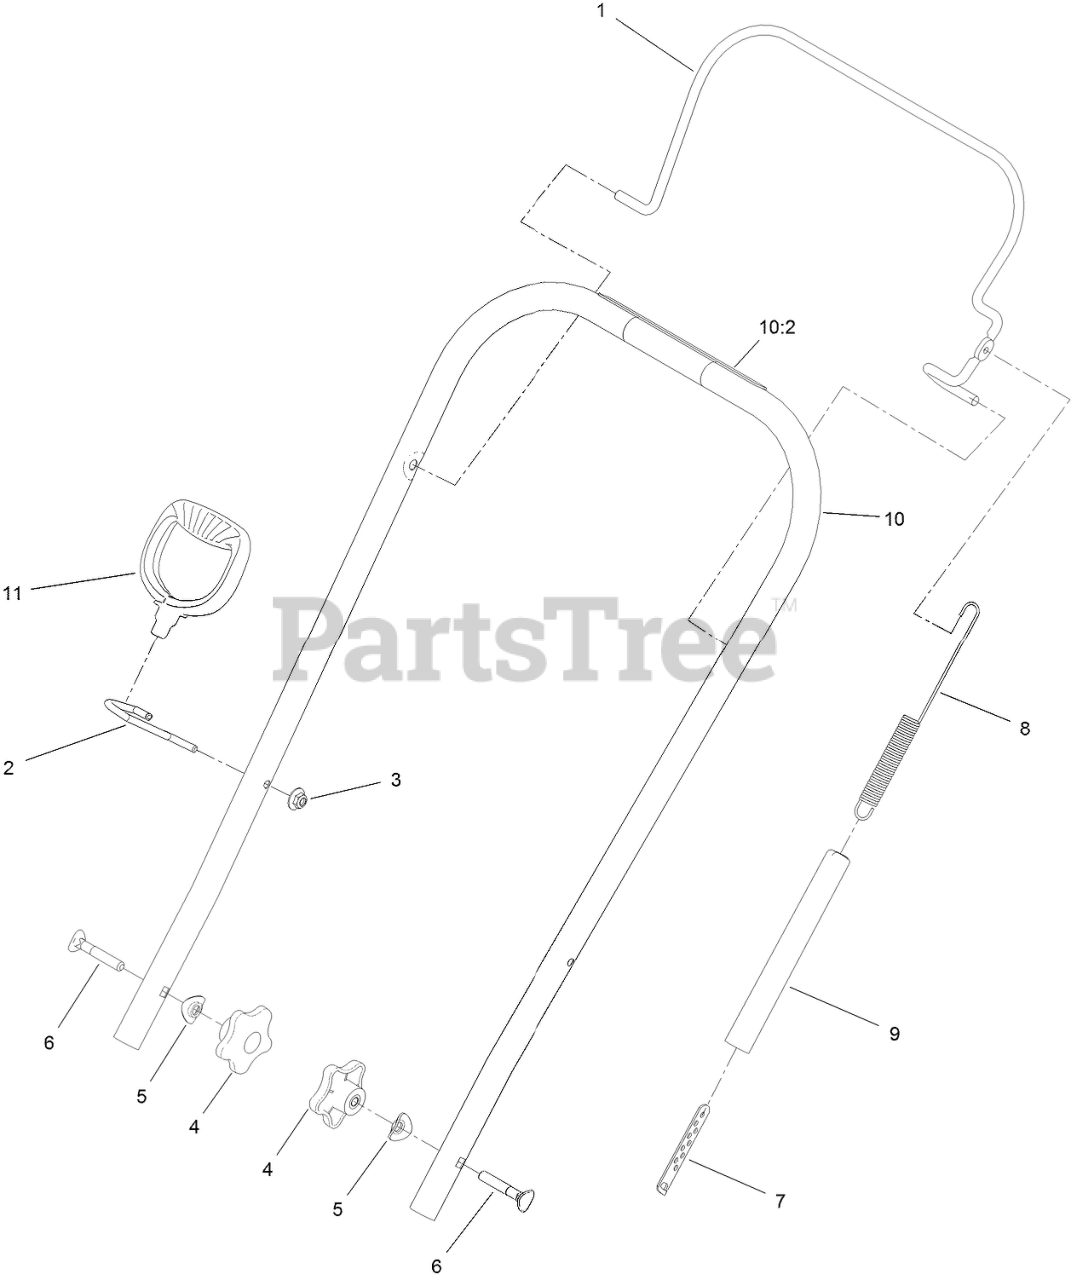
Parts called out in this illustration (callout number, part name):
1	BAIL-CLUTCH
2	GUIDE-ROPE
3	NUT-HF
4	KNOB-HANDLE
5	WASHER-CUP
6	SCREW-HANDLE
7	ADJUSTER-CLUTCH CABLE
8	SPRING-CLUTCH
9	COVER-SPRING
10	UPPER HANDLE ASM
10:2	DECAL-SAFETY
11	HANDLE-RECOIL
